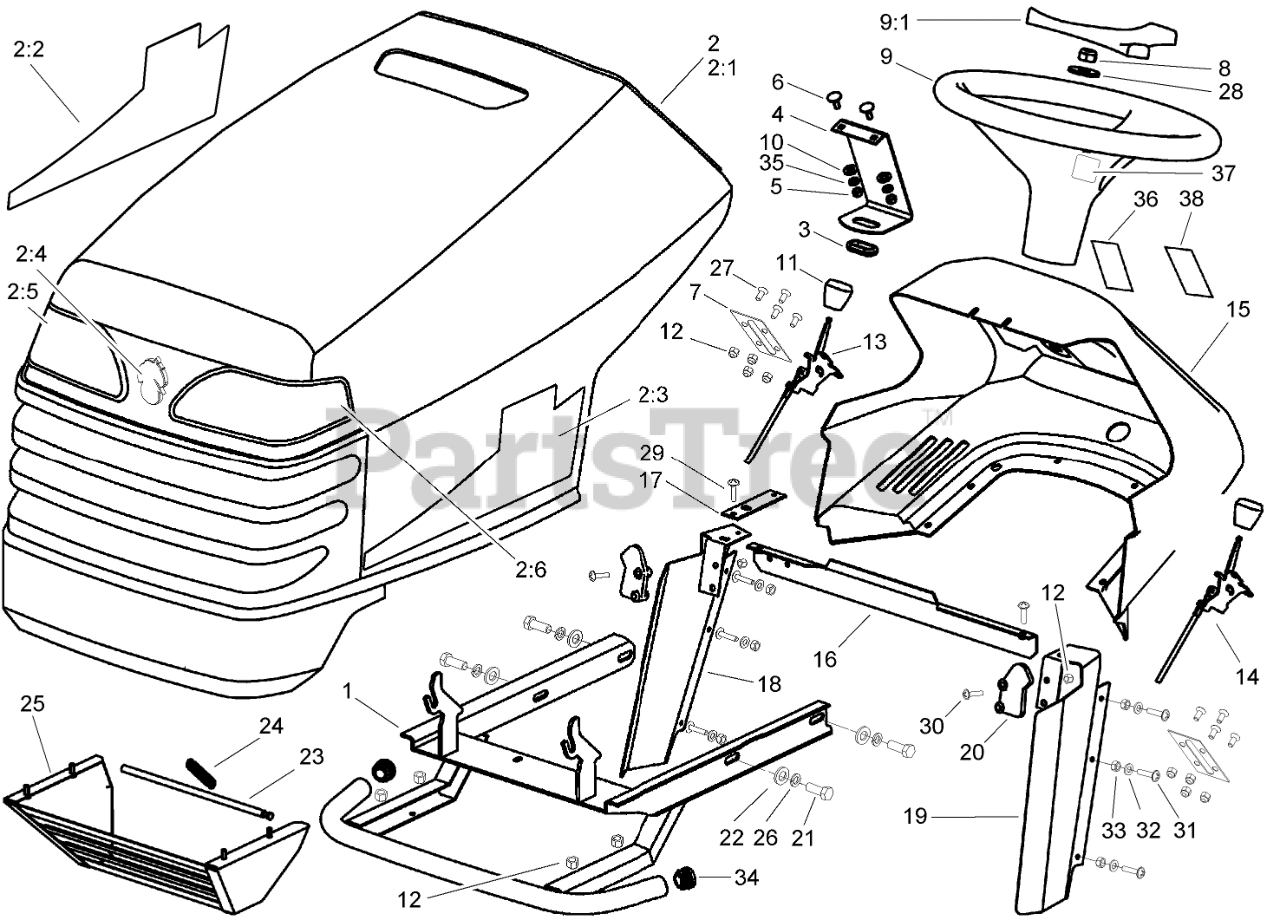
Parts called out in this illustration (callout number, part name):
1	SUPPORT-BUMPER
2	HOOD ASM
2:2	DECAL-HOOD, RH
2:3	DECAL-HOOD, LH
2:4	EMBLEM
2:5	LENS-HEADLAMP, RH
2:6	LENS-HEADLAMP, LH
3	BUSHING
4	HOLDER-TANK, FUEL
5	NUT-LOCK
8	NUT-LOCK
9	WHEEL-STEERING
9:1	COVER-WHEEL, STEERING
10	WASHER-PLAIN
12	NUT-LOCK
13	CONTROL-THROTTLE (TWIN)
14	CONTROL-CHOKE (TWIN)
15	PANEL-DASH
17	BRACKET
18	PANEL-RIGHT
19	PANEL-LEFT
20	LATCH-HOOD
21	SCREW-HH
22	WASHER-PLAIN
23	BAR-SAFETY
24	SPRING-HOOD
25	GUARD-MUFFLER
26	WASHER-LOCK, SPRING
28	Washer
32	WASHER
33	NUT-HEX
34	PLUG-END, TUBE
35	WASHER-LOCK, SPRING
36	DECAL
37	DECAL
38	DECAL-CHOKE/PTO
